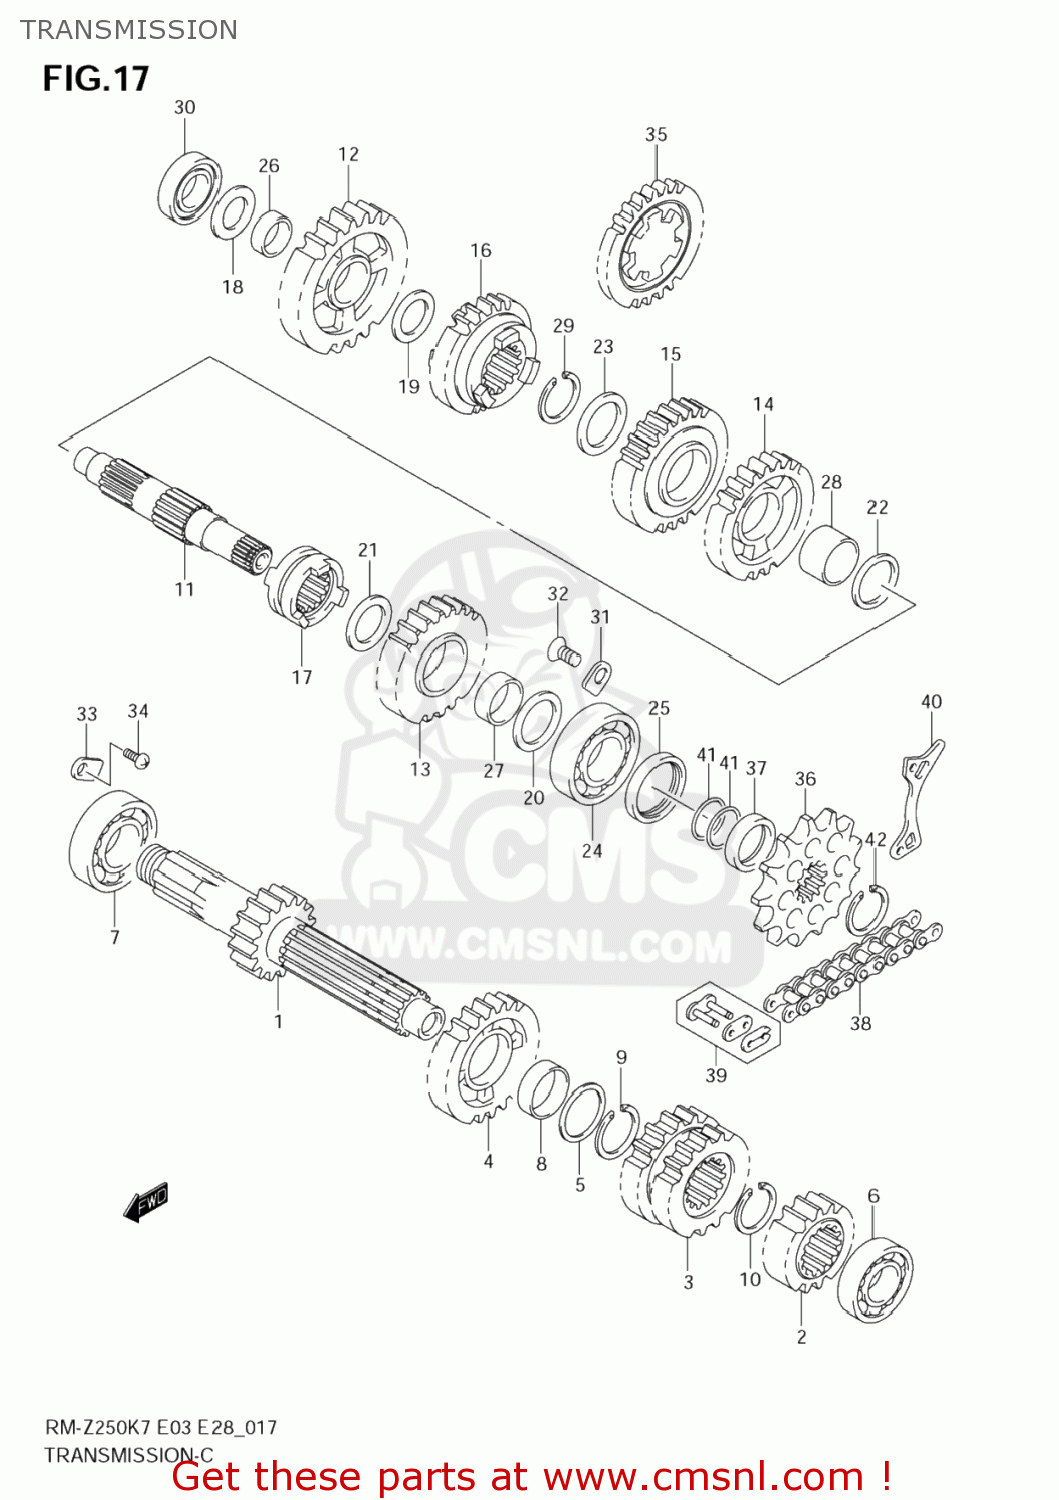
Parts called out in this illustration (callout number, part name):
1	SHAFT,COUNTER,
2	GEAR,2ND DRIVE
3	GEAR,3RD & 4TH
4	GEAR,5TH DRIVE(NT:22)
5	SHIM(24X29X1)
6	BEARING(17X40X9.5)
7	BEARING(22X50X14)
8	BUSH(24X27X0.0)
9	CIRCLIP
10	CIRCLIP
11	SHAFT,DRIVE
12	GEAR,1ST DRIVEN(NT:28)
13	GEAR,2ND DRIVE
14	GEAR,3RD DRIVEN(NT:25)
15	GEAR,4TH DRIVEN(NT:26)
16	GEAR,5TH DRIVEN(NT24)
17	DOG,SLIDING
18	SHIM(17X28X1)
19	SHIM(20X28X1)
20	SHIM(20X30X1)
21	SHIM(22X30X1)
22	SHIM(24X30X1)
23	SHIM(24X30X1)
24	BEARING(20X52X7.5)
25	SEAL,OIL(28X38X7.5)
26	BUSH(20X24X10)
27	BUSH(22X25X12)
28	BUSH(24X27X18)
29	CIRCLIP
30	BEARING(17X40X12)
31	RETAINER,COUNTER BEARING,R
32	SCREW(6X12)
33	RETAINER
34	BOLT(6X12)
35	GEAR,KICK STARTER IDLE
36	SPROCKET,ENGINE
37	SPACER,ENGINE SPROCKET
38	CHAIN(DID520DMA2,112L)
39	JOINT SET,CHAIN
40	PLATE,FRONT CH
41	O RING(D:1.9,ID:19.8)
42	CIRCLIP
